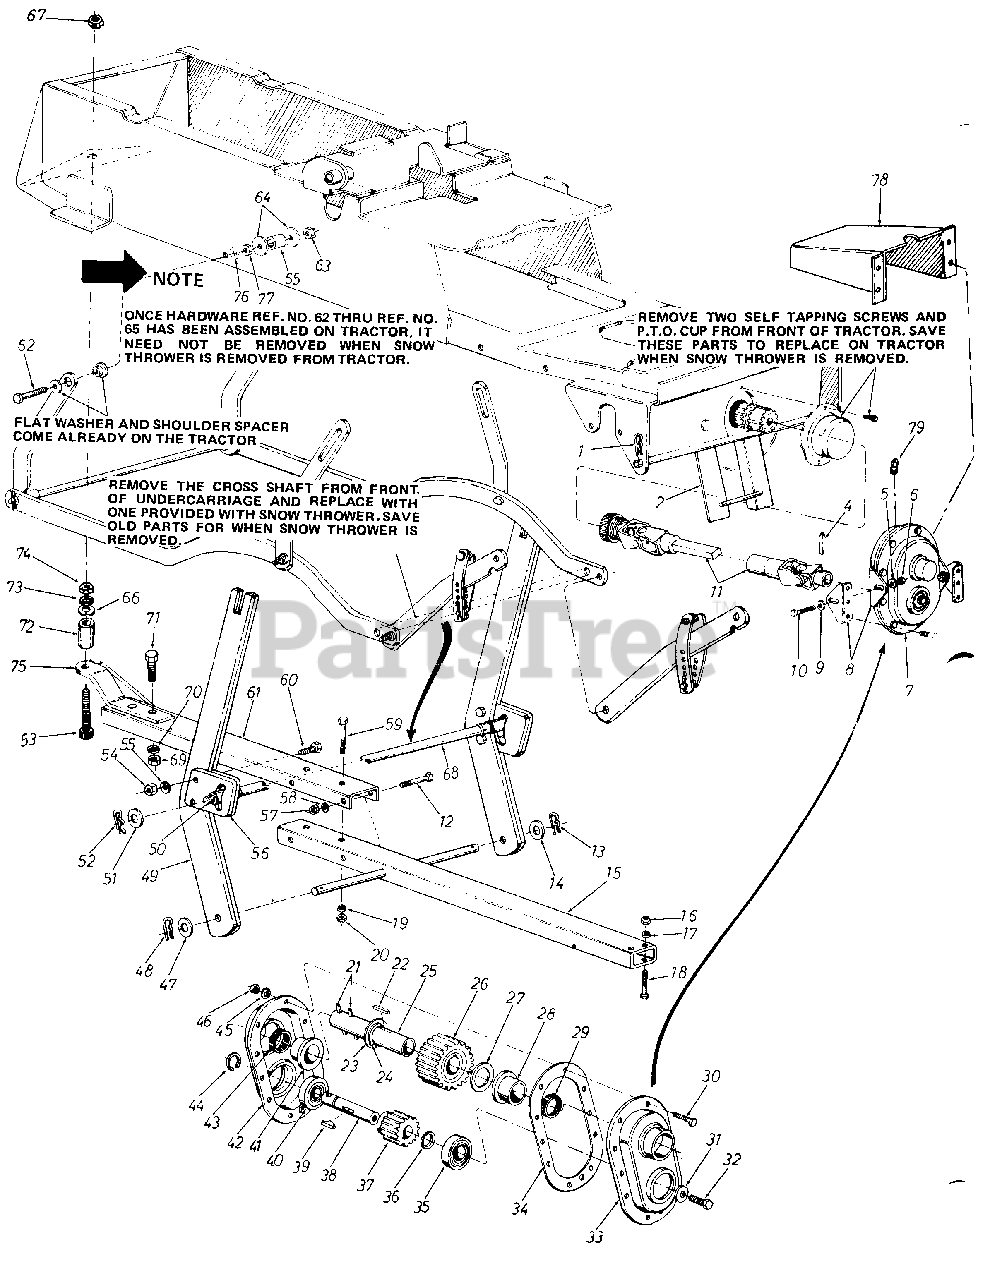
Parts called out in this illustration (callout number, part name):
1	Intern. Cotter Pin 3/4" Dia.
2	Guide Bracket Ass'y.
4	Spring Pin Spirol 1/4"Dia. x Lg.
5	BellevilleWash..341" I.D. x.88" O.D.
6	Hex Nut 5/16-18 Thd.*
7	Gear Box Ass'y. Comp.
8	Gear Box Support Brkt.
9	Belleville Wash. .341 " I.D. x .88" O.D.
10	Hex Sc 5/16-18 x .75" Lg.
11	Universal Drive Shaft Ass'y.
12	Hex Scr. 3/8-24 x 4.50" Lg.*
13	Hair Pin Cotter
14	Fl.-Wash. .62" I.D. x 1.12" O.D.
15	Lift Shaft Ass'y.
16	Hex Ins. Jam L.-Nut 3/8-24 Thd.
17	L.-Wash. 3/8" Scr.*
18	Hex Scr. 3/8-24 x 2.75" Lg.*
19	L.-Wash. 3/8" Scr.*
20	Hex Ins. Jam L.-Nut 3/8-24 Thd.
21	Spring Pin Spirol 5/16" Dia. x 1.75" Lg.
22	Sq. Key 1/4" x 1/4" x 1.00" Lg.
23	Fl.-Wash. 1.31" I.D. x 2.00" O.D. x.060
24	Snap Ring for 1.25" Dia. Shaft
25	Gear Shaft
26	28 Teeth Spur Gear
27	Fl.-Wash. 1.31" I.D. x 2.00 O.D. x.060
28	Flange Bearing 1.25" I.D. x 1.75 O.D.
29	Oil Seal 1.25" I.D. x 1.75" O.D. O.D. x .26
30	Hex Scr. 1/4-28 x .88" Lg.
31	Fl.-Wash. .40 I.D. x 1.25" O.D. x .160
32	Hex L.-Scr. 3/8-24 x 1.00" Lg.
33	Complete Gear Housing Half-L.H.
34	Gasket
35	Ball Bearing 1.00" I.D. x 2.00"O.D.
36	Fl.-Wash. 1.03" I.D. x 1.63" x .090
37	15 Teeth Spur Gear
39	Woodruff Key 1/4" x 3/4" Dia.
40	Ball Bearing 1.00" I.D. x 2.00"O.D.
41	Flange Bearing 1.25" I.D. x 1.75" O.D.
42	Complete Gear Housing Half-R.H.
43	Oil Seal 1.25" I.D. x 1.75" O.D. x .26
44	Snap Ring for 1.00" Dia. Shaft
45	SpringWash. 1/4" I.D.
46	Hex Nut 1/4-28 Thd.
47	Fl.-Wash. .62" I.D. x 1.12" O.D.
48	Hair Pin Cotter
51	Fl.-Wash. .62" I.D. x 1.12" O.D.
52	Hair Pin Cotter
53	Hex Bolt 5/8-18 x 4.00" Lg.
54	Hex Nut 5/16-18 Thd. *
55	L.-Wash. 5/16" Scr.
58	L.-Wash. 3/8" Scr.*
59	Hex Scr. 3/8-24 x 2.75"
60	Hex Scr. 5/16-18 x 1.00" Lg. *
61	Lift Bracket
62	Hex Scr. 3/8-24 x 2.50"
63	Hex Jam L.-Nut 3/8-24 Thd.
64	Fl.-Wash...375 I.D. x 1.00" O.D x .135"
65	Spacer .275 I.D. x .625 O.D. x .440
66	Fl.-Wash. .66" I.D. x 1.25" O.D. x .l 00
67	Hex Jam L.-Nut 5/8-18 Thd.
68	Cross Shaft Ass'y.
69	Hex Nut 1/2-13 Thd.*
70	L.-Wash. 1/2" Scr.*
71	Hex Scr. 1/2-13 x 1.25"
72	Bushing
73	L.-Wash. 5/8" Scr.*
74	Hex Jam Nut 5/8-18 Thd.
77	Hex Nut 3/8-24 Thd. *
78	Drive Shaft Cover
79	Grease Fittinq
